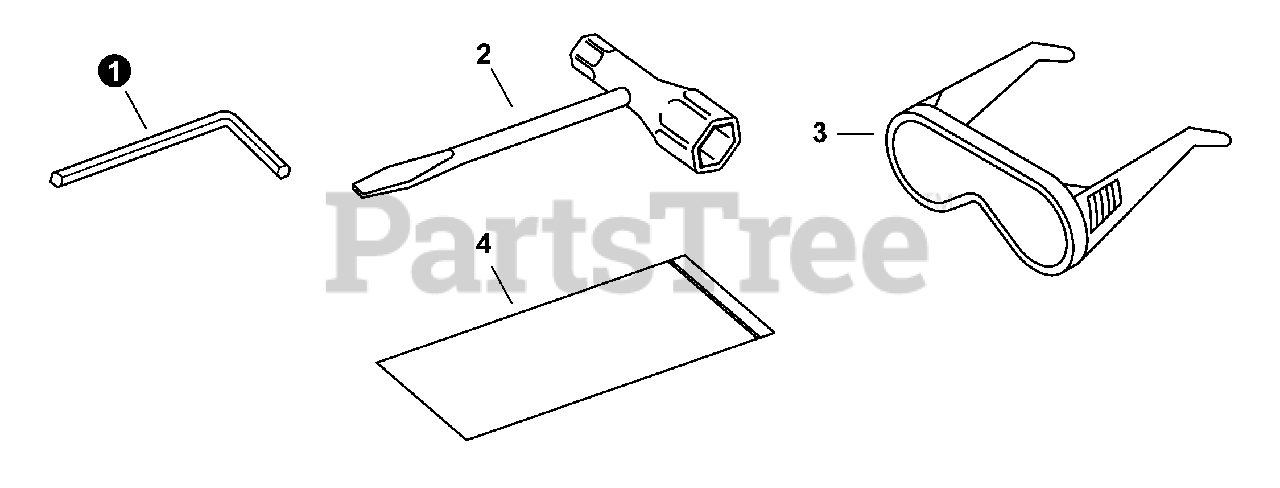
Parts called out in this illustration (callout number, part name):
1	WRENCH, ALLEN 4MM
2	T-WRENCH 16×13
3	GLASSES, SAFETY
4	BAG, TOOL
